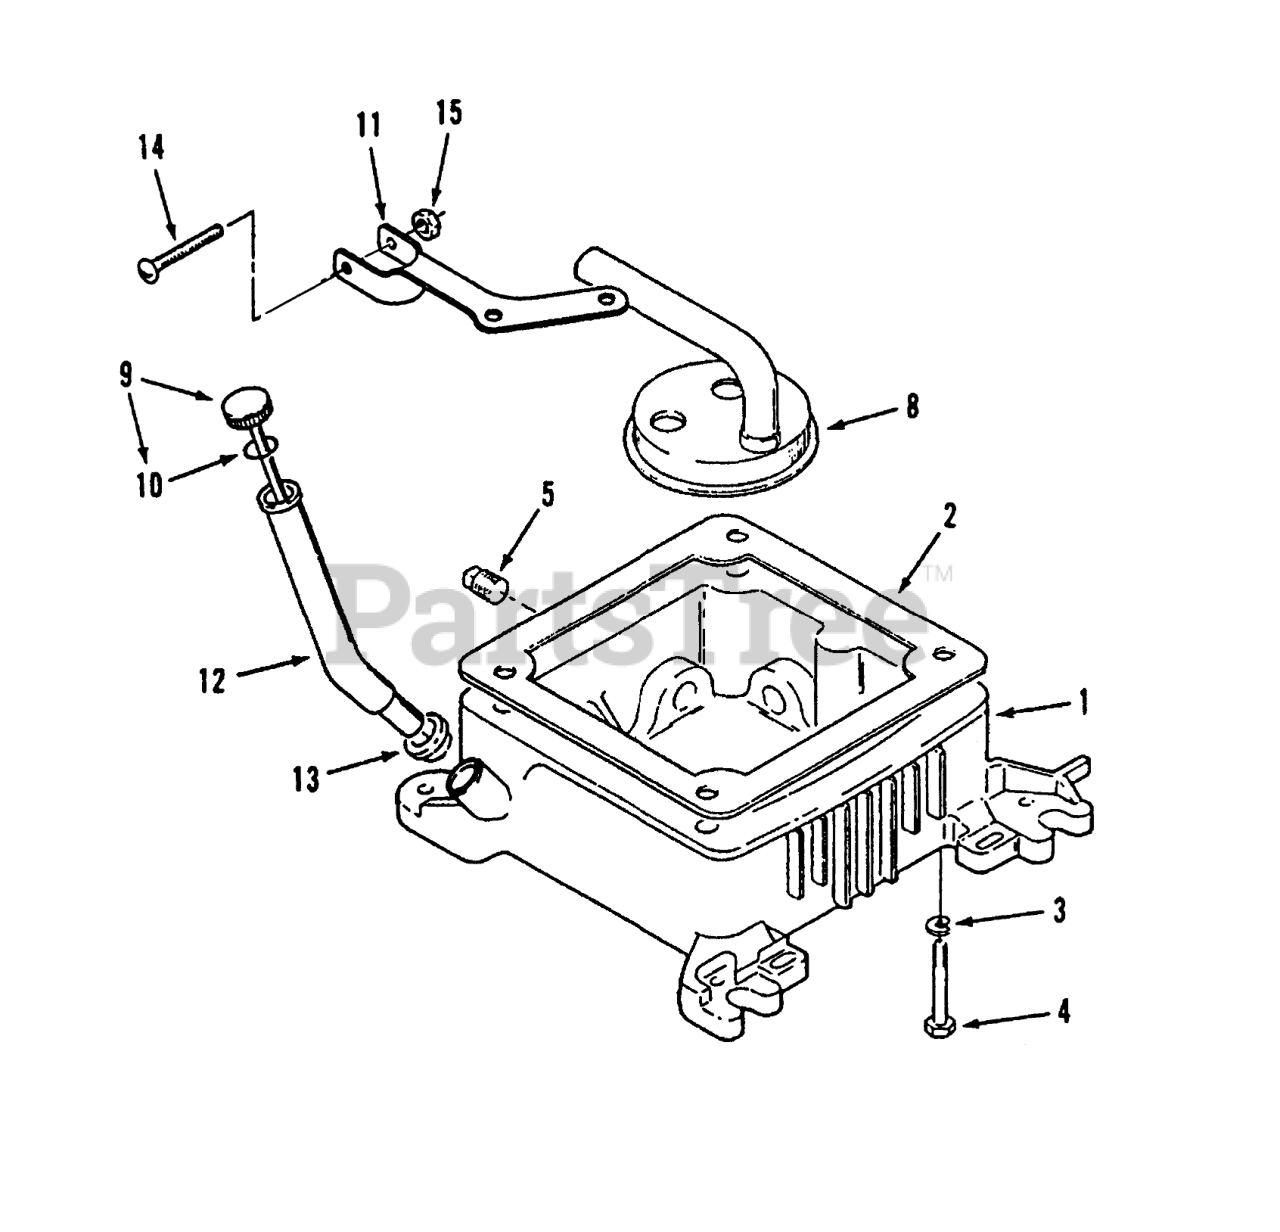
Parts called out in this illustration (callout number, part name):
1	Base-Oil (Includes All Plugs & Plug Gasket)
2	GASKET
3	WASHER-FLAT
4	HHCS 3/8-16 X 3 3/4
5	PLUG - SQUARE HEAD
8	Cup-Oil Pump Intake
9	Cap-Oil Fill & Indicator (Includes O-Ring)
10	O-Ring
11	BRACKET-FILL TUBE
12	TUBE-OIL FILL
13	Seal
14	SCREW - PAN HEAD
15	NUT - SPEED
